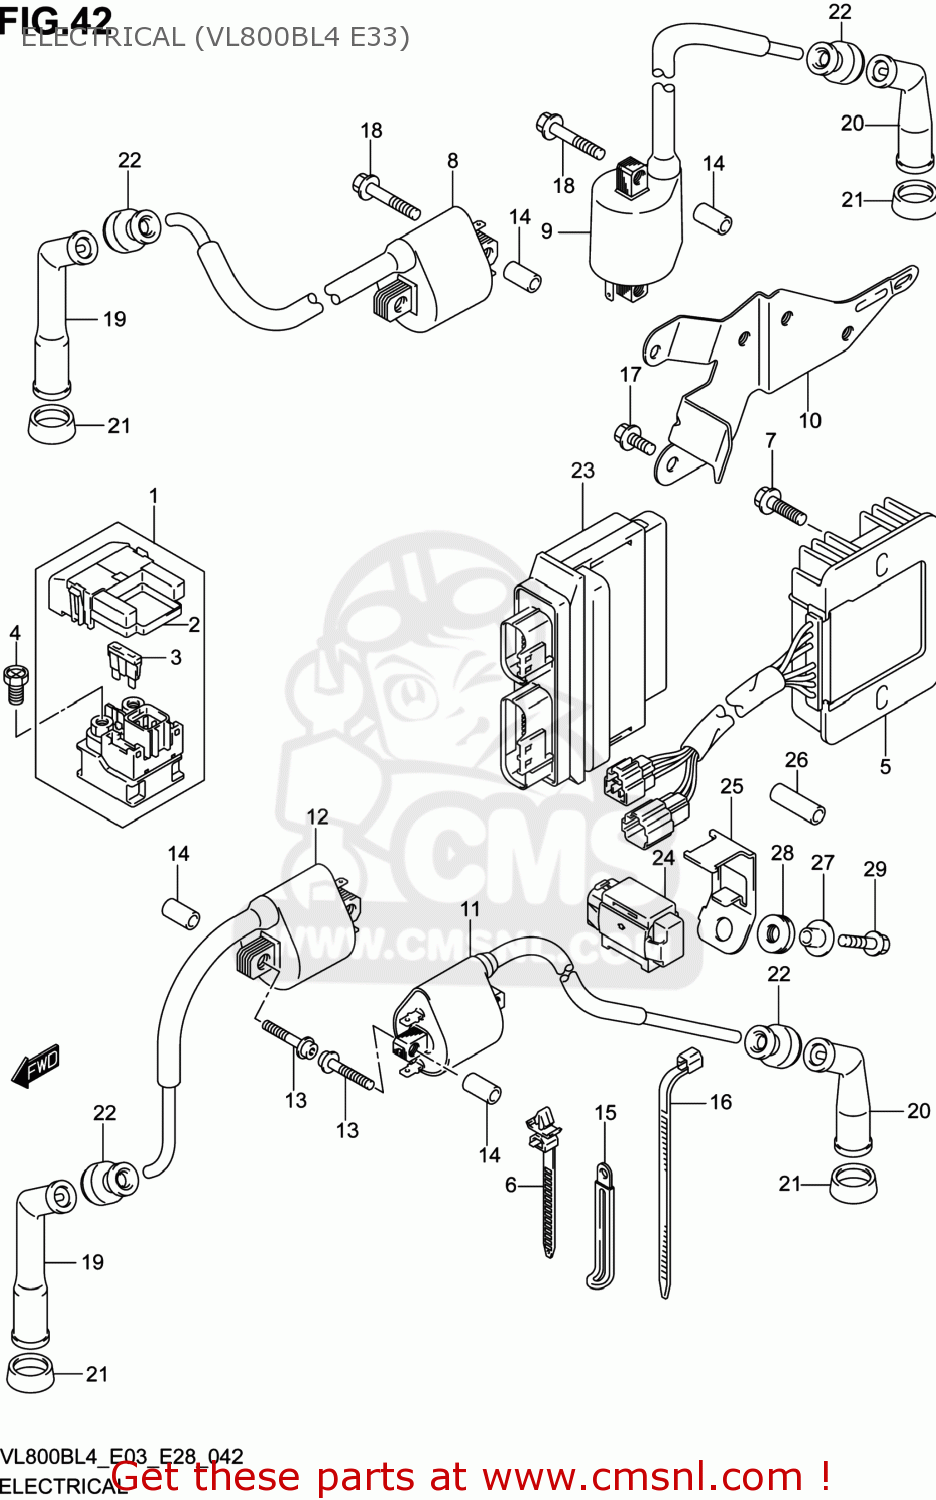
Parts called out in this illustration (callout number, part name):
1	RELAY ASSY,STARTING MOTOR
2	COVER
3	FUSE(30A)
4	SCREW(6X8)
5	RECTIFIER ASSY
6	CLAMP(L:90)
7	SCREW
8	COIL ASSY,IGNITION RR
9	COIL ASSY,IGNITION RR
10	BRACKET,IGNITION COIL RR
11	COIL ASSY,IGNITION FR
12	COIL ASSY,IGNITION
13	BOLT(5X35)
14	SPACER(6.4X10X18)
15	CLAMP(L:80)
16	CLAMP(L:190)
17	BOLT
18	BOLT
19	CAP,SPARK PLUG
20	CAP,SPARK PLUG
21	SEAL,SPARK PLUG
22	SEAL,HIGH TENSION CORD
23	CONTROL UNIT,FI
24	SENSOR ASSY,FUEL CUT
25	BRACKET,FUEL CUT SENSOR
26	HOSE(5X8.2X600)
27	SPACER(6.2X8.4X6.9)
28	CUSHION
29	BOLT
